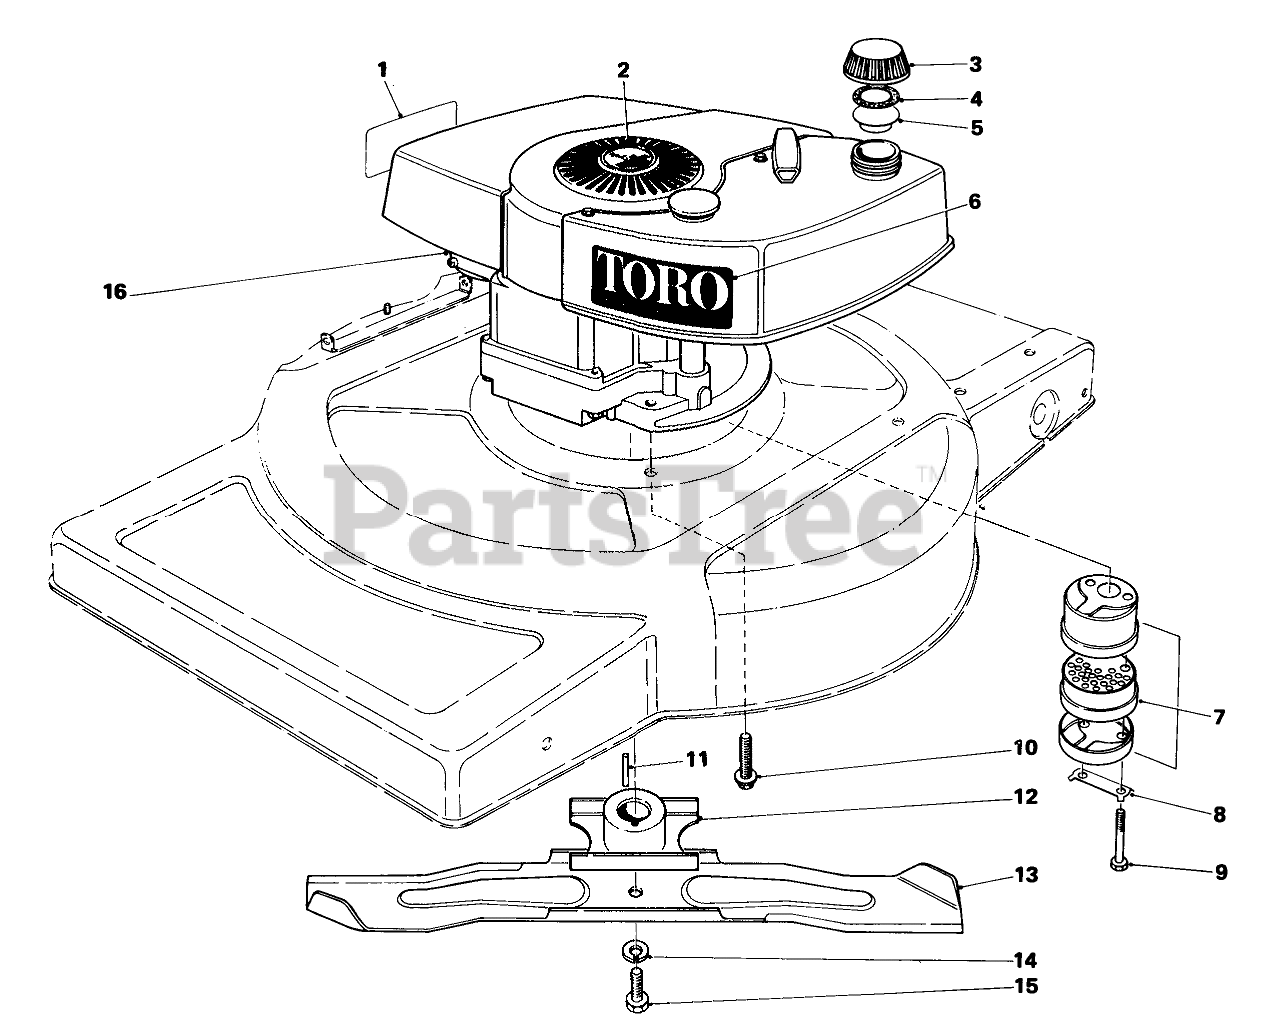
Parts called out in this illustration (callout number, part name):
1	Decal-Maintenan
2	PLUG BUTTON
3	Gas Cap (Incl. Ref. #4 & 5)
4	GASKET
5	GAS CAP BAFFLE
6	Decal
7	Muffler Assembly (Incl. Ref. #8 & 9)
8	CLIP - LOCKING
9	SCREW-HH
10	SCREW-HWHTF
11	KEY-SQUARE
12	Blade Retainer
13	Blade
14	WASHER-LOCK
15	SPECIAL SCREW
16	Engine
